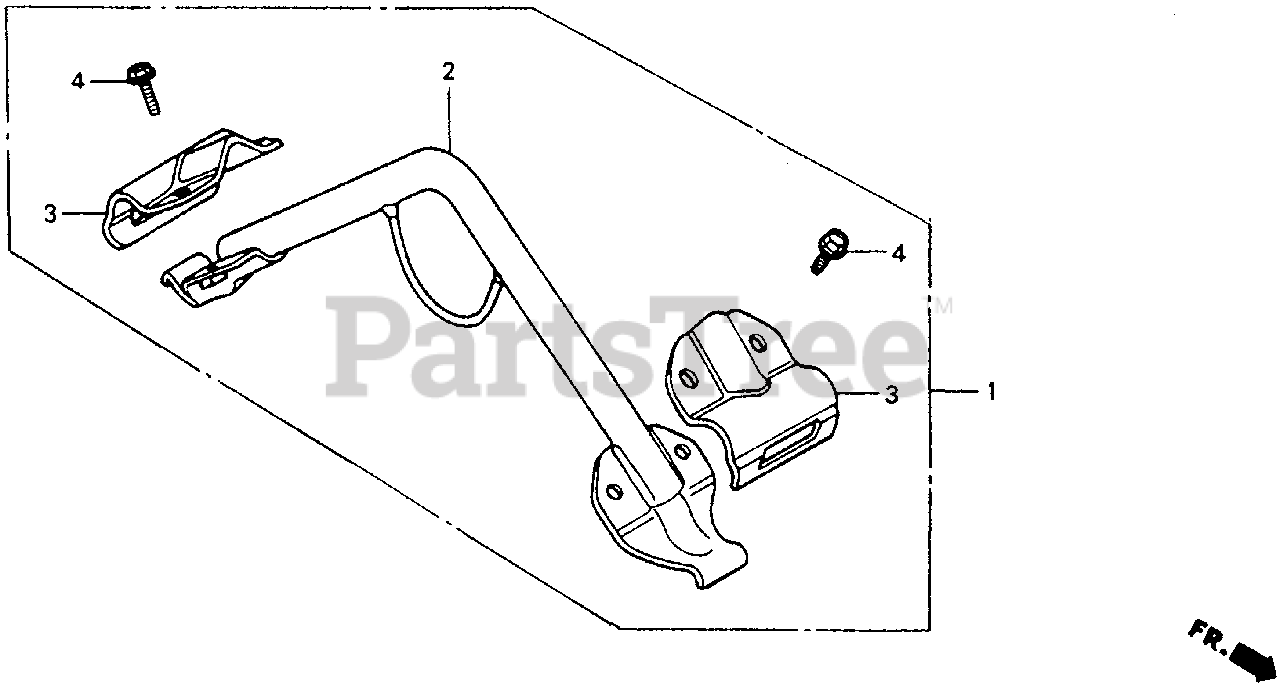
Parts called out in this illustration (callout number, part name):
1	HANGER KIT Use up to Frame SN 1081652.
1	HANGER KIT
2	HANGER Use up to Frame SN 1081652.
2	HANGER
3	BRACKET, HANGER (UPPER)
4	BOLT, FLANGE (8X16)
